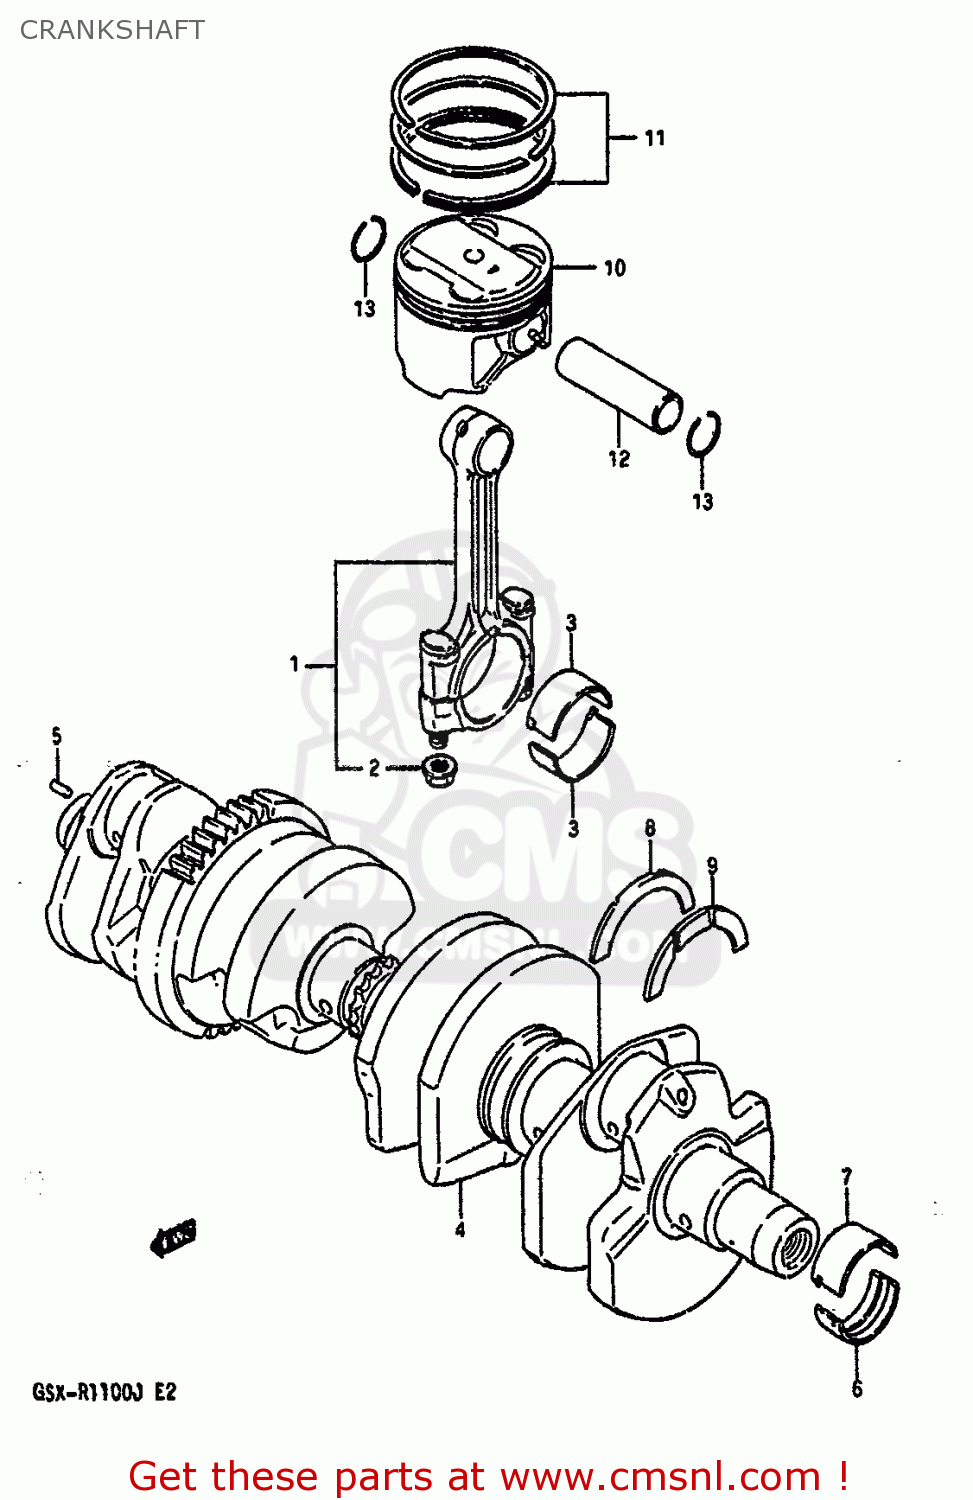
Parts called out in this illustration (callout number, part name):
1	CONNECTING ROD ASSEMBLY
2	NUT
3	BEARING,CRANK PIN
4	CRANKSHAFT
5	PIN
6	BEARING,CRANKSHAFT LWR
7	BEARING,CRANKSHAFT UPR
8	PLATE,CRANK THRUST
9	PLATE,CRANK THRUST
10	PISTON (OS:0.5)
11	RING SET,PISTON
12	PIN,PISTON
13	CIRCLIP,PISTON PIN
